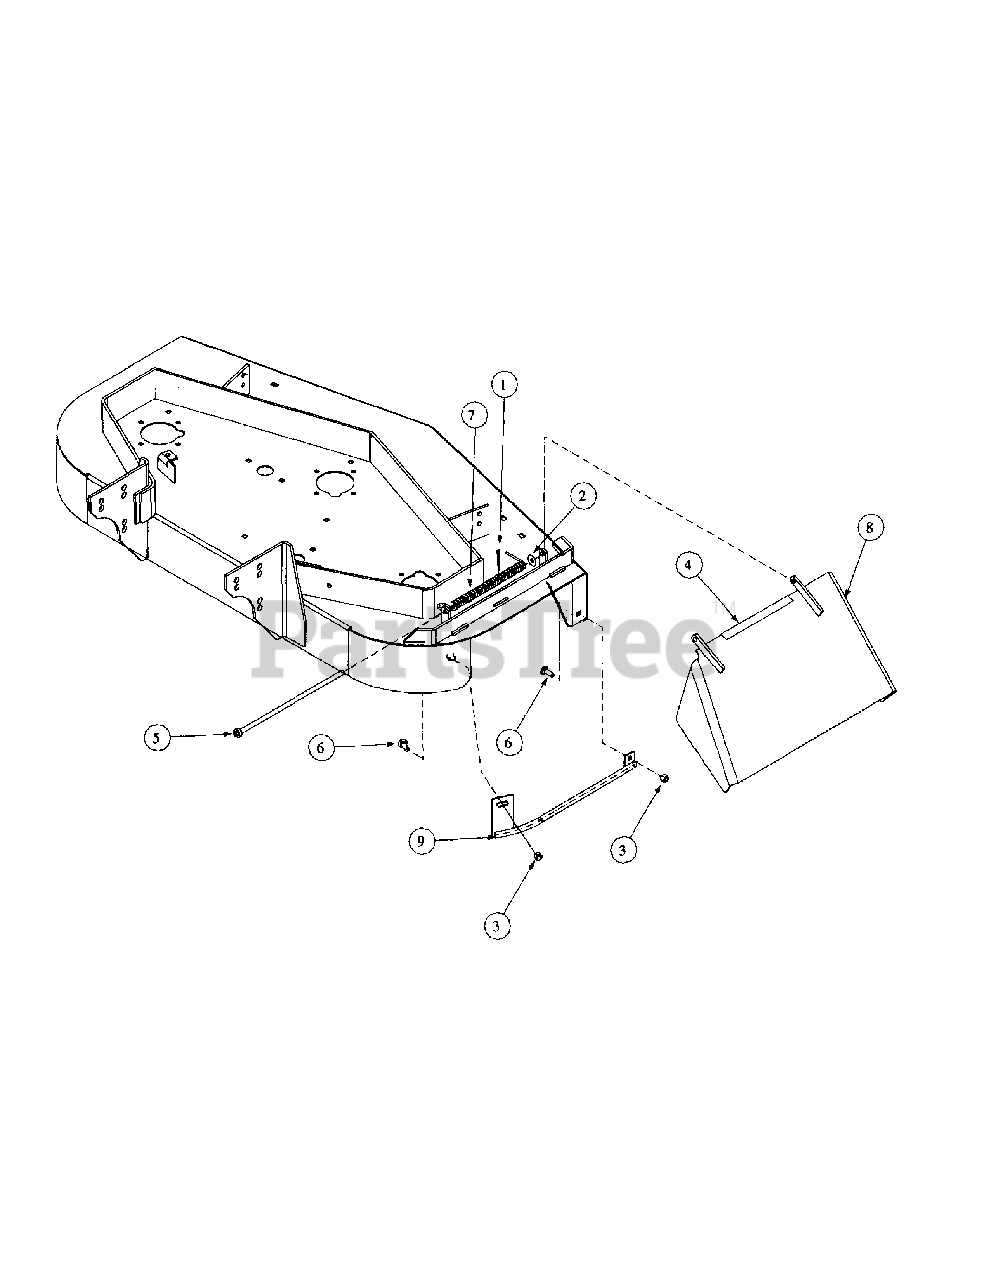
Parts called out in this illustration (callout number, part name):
1	Cotter Pin, 5/32 x 1-1/2 Zinc
2	Flat Washer, 3/8 Zinc
3	Lock Nut, Nylon Insert, 3/8-16
4	Decal, Cut Line
5	Pin Deflector Assembly, Weldment
6	Carriage Bolt, 3/8-16 x 2
7	Torsion Spring
8	Chute Assembly
9	Stiffner Assembly, 48
